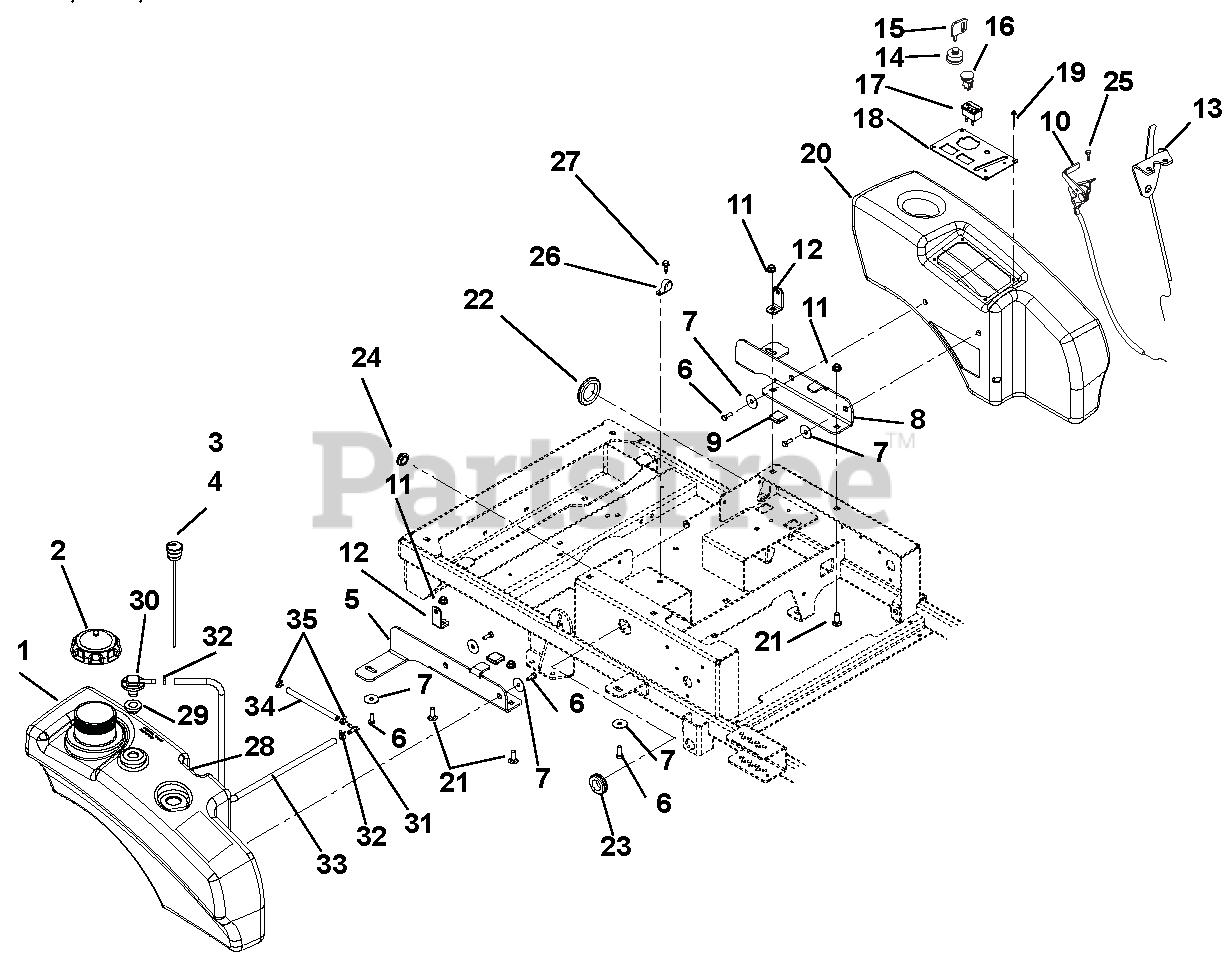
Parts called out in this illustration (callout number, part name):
1	KIT, XL TANK REPLACEMENT
2	CAP, FUEL
3	GAUGE, REMOTE FUEL 10.0"
4	GROMMET, FUEL GAGE
5	BRKT, RH REAR TANK MOUNT
6	BLT-SERHFWH .312-18X.50 YWZC
7	WSHR-FL-STL .347X1.254X.048YWZ
8	BRKT, LH REAR TANK MOUNT
9	GRIP, RUBBER (1.0X1.0X.187)BLK
10	CABLE, XL THROTTLE
11	@NUT-LK-NYL-FLG .38-16 YWZC
12	BRKT, HOOD PIVOT
13	CABLE, XL CHOKE
14	KEY SWITCH
15	KEY -W/CAP
16	SWITCH, CLUTCH
17	HOUR METER - DIGITAL
18	CONTROL PANEL
19	RIVET, PLASTIC .195 DIA.
20	FENDER, XL
21	@BLT-RDHDSQNK .38-16X1.00 G5YZ
22	GROMMET 1.70ID X 2.0OD
23	GROMMET 1.0ID X 1.38 OD
24	GROMMET,RUBBER 5/8 ID/1.13 OD
25	@SCR-TAP 10-24X.50 HWH TR YWZC
26	CLAMP, CUSHIONED STEEL .75
27	@SCR-TAP .38-16X.50 HWH TR YWZ
28	ASM, FUEL PICK-UP - XL
29	GROMMET, REMOTE VENT NITRILE
30	VENT, ROLL-OVER (.25"ID HOSE)
31	FITTING-3/16X1/4 90DEGREE VAC
32	CLAMP, FUEL LINE
33	HOSE, .25 LOW-PERM BULK GAS
34	HOSE, .188 LOW-PERM BULK GAS
35	CLAMP-HOSE, SPRING .188
